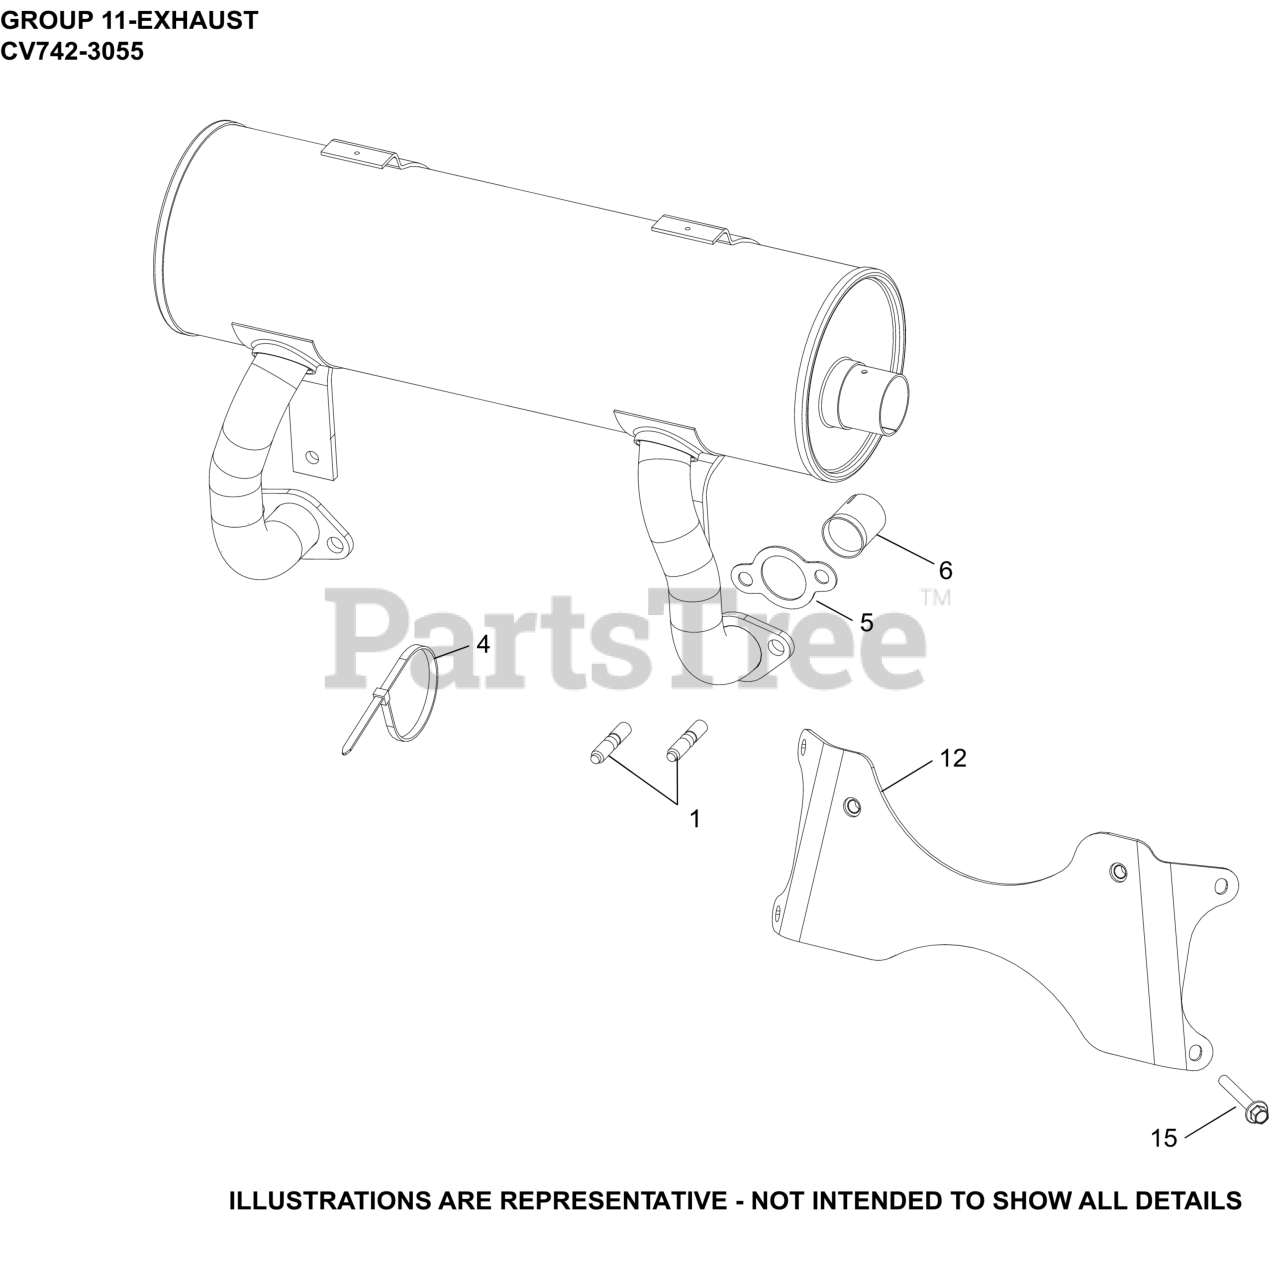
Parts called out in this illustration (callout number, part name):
1	STUD, METRIC EXHAUST
5	GASKET, EXHAUST MANIFOLD
6	LINER, EXHAUST PORT
12	BRACKET, MAIN SUPPORT
15	SCREW, FLG M6X1.0X40
